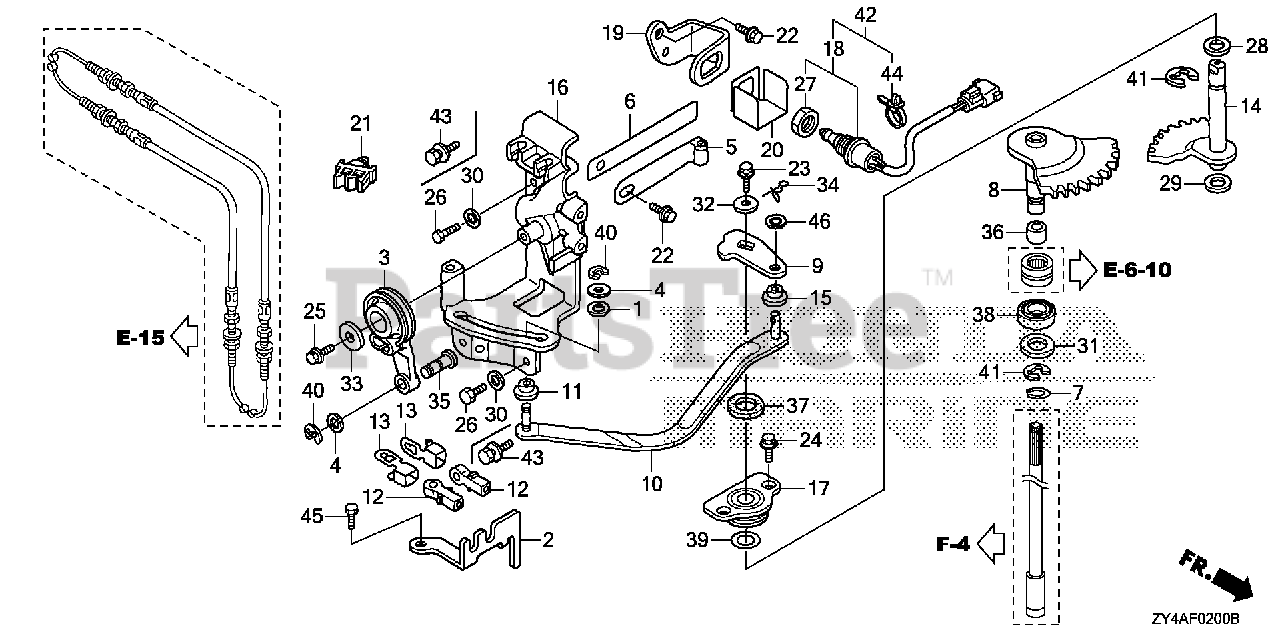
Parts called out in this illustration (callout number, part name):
1	WASHER, AIR CLEANER COVER SETTING
2	PLATE, REMOTE CONTROL CABLE
3	ARM, THROTTLE
4	WASHER, PIVOT
5	SPRING, CLICK
6	SPRING, CLICK ASSIST
7	RING, STOPPER
8	SHAFT, SHIFT (A)
9	ARM, SHIFT
11	COLLAR, SHIFT SLIDER
12	PIVOT, SHIFT
13	PLATE, LOCK
14	SHAFT, SHIFT (B)
15	BUSH, SHIFT ARM
16	BRACKET, SHIFT LINK
17	HOLDER, SEAL
18	SWITCH ASSY., NEUTRAL
19	BRACKET, NEUTRAL SWITCH
20	COVER, NEUTRAL SWITCH
21	CLIP, BRAKE PIPE
22	BOLT, FLANGE (6X14) (CT200)
23	BOLT, FLANGE (6X16)
24	BOLT, FLANGE (6X11)
25	BOLT, FLANGE (6X12)
26	BOLT, HEX. (6X16)
27	NUT, HEX. (20MM)
28	WASHER, THRUST (14MM)
29	WASHER B, THRUST (14MM)
29	WASHER, SHIFT SHAFT
30	WASHER, PLAIN (6MM)
32	WASHER, PLAIN (6MM)
33	WASHER, PLAIN (6MM)
34	PIN, SNAP (6MM)
36	RING (INNER) (15X20X13)
37	OIL SEAL (14X26X6)
38	SEAL, WATER (14X26X8)
39	O-RING (26.9X2.4) (NOK)
40	E-RING (4MM)
41	E-RING (12MM)
43	BOLT-WASHER (6X16)
45	BOLT, HEX. (6X16)
46	WASHER, PLAIN (6MM)
